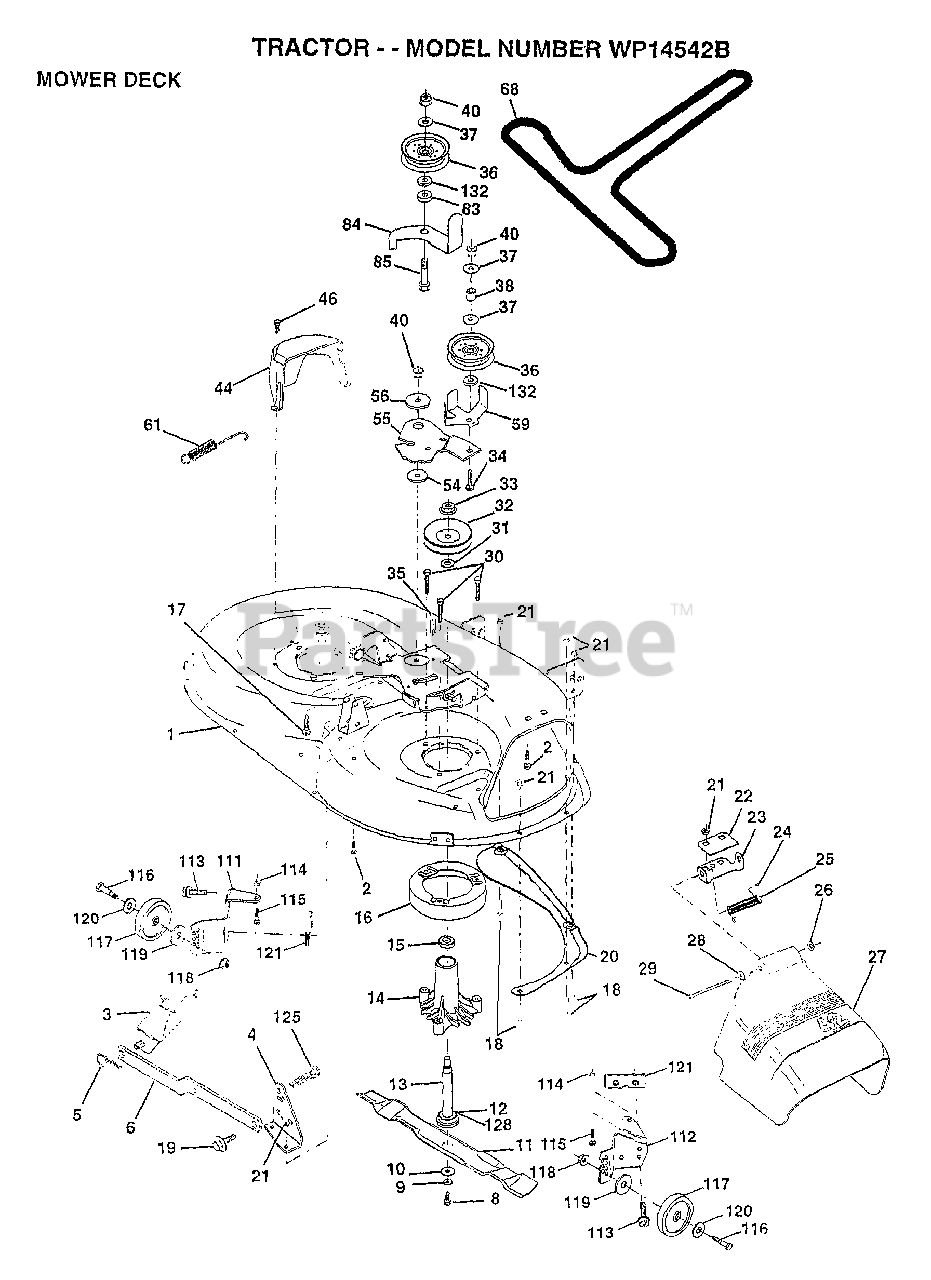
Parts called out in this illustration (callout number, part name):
1	DECK.WELD.42.
2	BOLT
3	BRKT ASM SWAY BAR
4	BRKT DECK SW BAR
8	BLADE BOLT
10	WASHER.HARD.BLADE
11	"BLADE.42"" HIPERF"
12	BEARING.BALL
14	HSG ASM MANDREL
15	BEARING
16	STRIPPER RND MWR
17	BOLT CARRIAGE
18	BOLT
19	BOLT SHD 5/16-18
22	STIFFENER BRKT
23	DEFLECTOR BRKT
24	CAP-SLEEVE LT
25	SPRING TORSION
26	NUT PUSH M
27	DEFLECTOR.SHIELD
28	WASHER
29	HINGE ROD
31	WASHER
32	PULLEY.MANDREL.42
34	BOLT
35	XMAS TREE FASTNER
36	FLAT IDLER PULLEY
37	WASHER
44	GUARD MAND LH BLK
46	SCREW.1/4-20X5/8
54	HARDENED WASHER
56	SPACER RETAINER
59	GUARD IDLER TUV
61	SPRING.EXTENSION
68	BELT.V.T-PATH
83	WASHER
84	"KEEPER-BELT,FIXED"
85	BOLT RDHD 3/8-16
111	BRACKET.GWHL.LH.
112	BRACKET.GWHL.RH.
113	SCREW
116	BOLT M
117	WHEEL.GAGE.BLK.PL
118	LOCKNUT
119	WASHER
120	WASHER
121	BRACKET.EXTRD.GWL
125	COTTER PIN
128	WASHER.FELT.
132	WASHER GT
